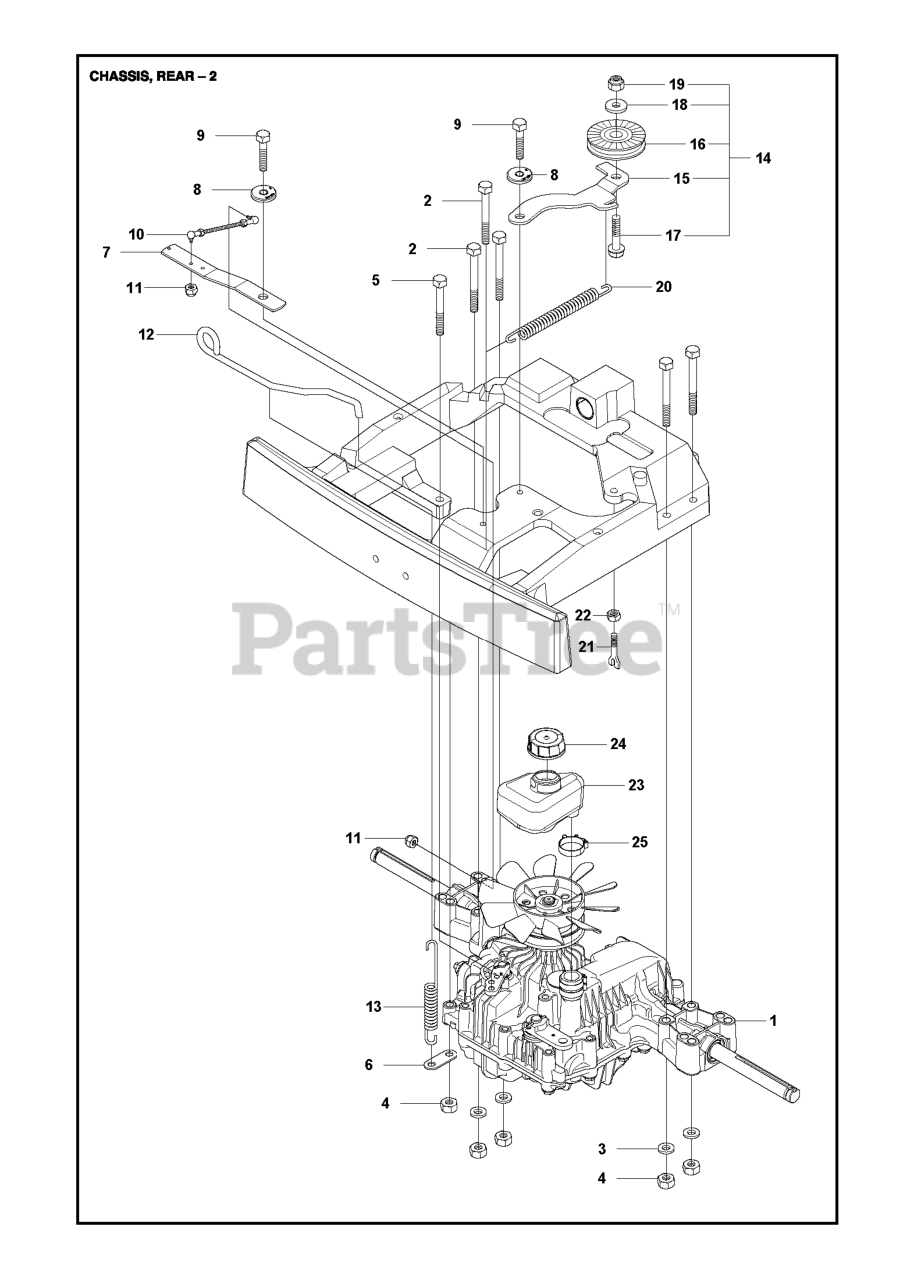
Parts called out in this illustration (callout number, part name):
2	VALVE STEM LT
3	RIM ASSEMBLY, FRONT
4	TUBE.16X6.5/7.5-8
5	TIRE HEAVY DUTY
6	FITTING LT
7	BEARING T
8	CAP, AXLE BLK
9	TIRE HEAVY DUTY
10	TUBE.23X9.5-12
11	RIM.ASM.12X7.REAR.SILVER
12	ZERK FITTING M
